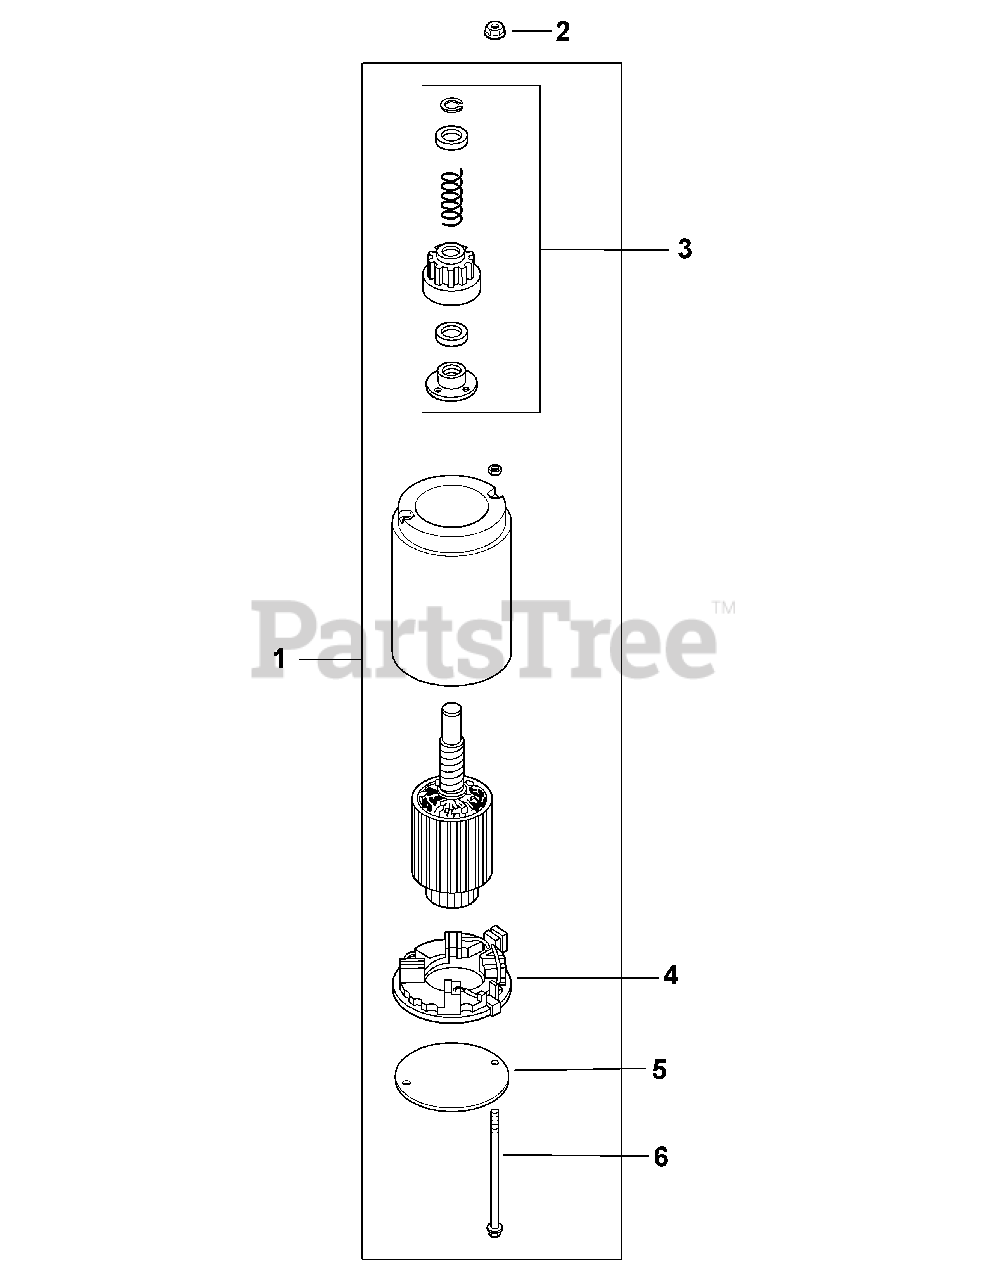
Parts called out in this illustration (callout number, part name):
1	Starter Assembly (Inc. 3-6)
2	Free Spinning Flg. Nut, #10-24
3	Drive Kit (J.E.)
5	Drive End Cap (J.E.)
